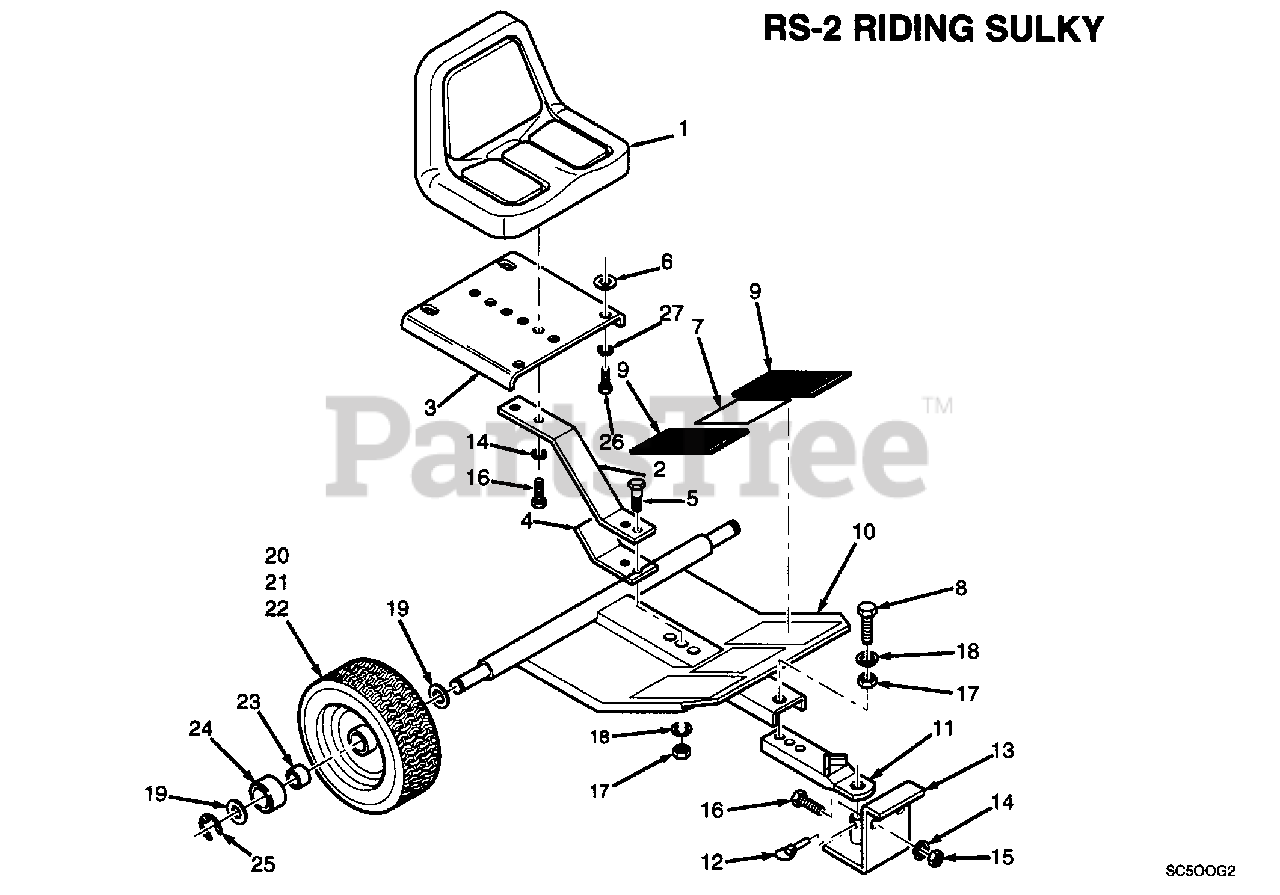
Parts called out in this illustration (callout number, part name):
1	SEAT ASSEMBLY
2	SEAT SPRING
3	SEAT MOUNTING PLATE
5	HEX HEAD BOLT 7/16-14 X 1-1/2"
6	WASHER 3/8 1-1/2" OD
7	DECAL
8	HEX HEAD BOLT 7/16-14 X 1"
9	PAD, NON SKID
10	FRAME WELDMENT
11	HITCH EXTENSION WELDMENT
12	QUICK PIN
13	HITCH BRACKET
14	LOCKWASHER 3/8" SPRING
15	HEX NUT 3/8-16
16	HEX HEAD BOLT 3/8-16 X 1"
17	HEX NUT 7/16-14
18	LOCKWASHER 7/16" SPRING
19	WASHER 1" ID
20	WHEEL ASSEMBLY(INCL. 21-24)
21	TIRE ONLY
22	RIM ONLY
23	BEARING ONLY
24	RETAINING CAP
25	RETAINING RING 1.0 EXT. "E"
26	HEX HEAD BOLT 5/16-18 X 3/4"
27	LOCKWASHER 5/16"
